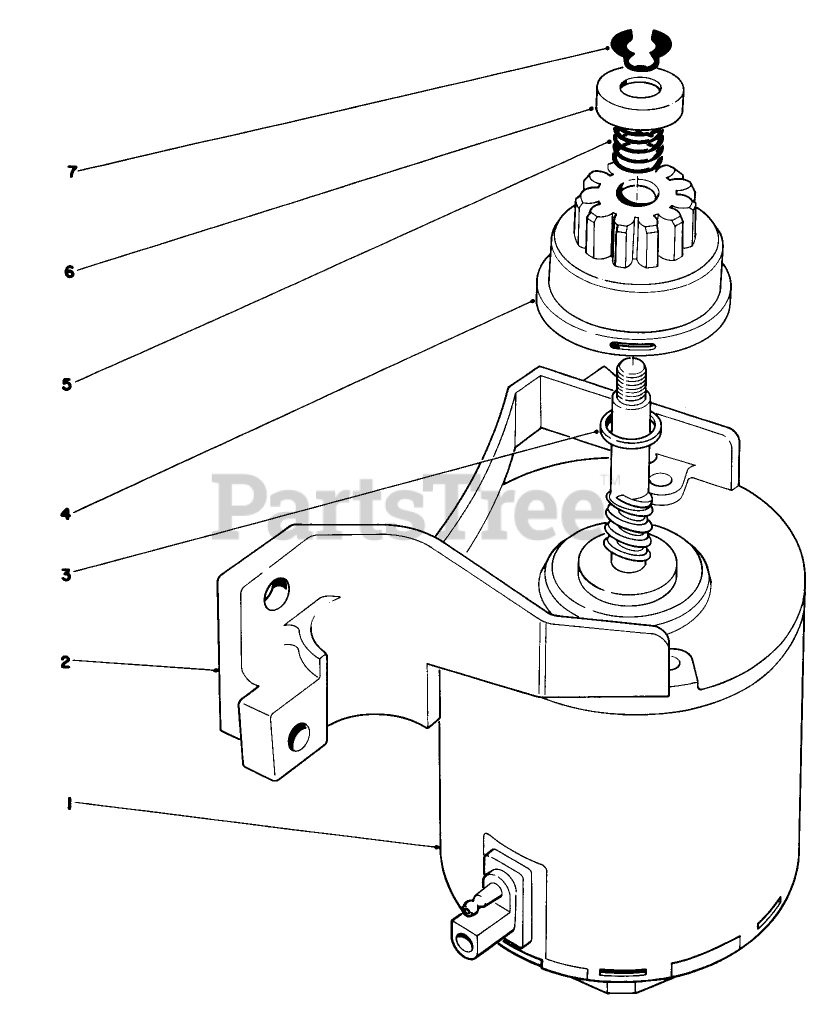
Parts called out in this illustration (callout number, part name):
1	END FRAME W/BRUSH
2	BRKT END FRAME
3	SPACER
4	PINION ASM
5	COMPRESSION SPRING
6	PINION STOP
7	Retaining Ring
